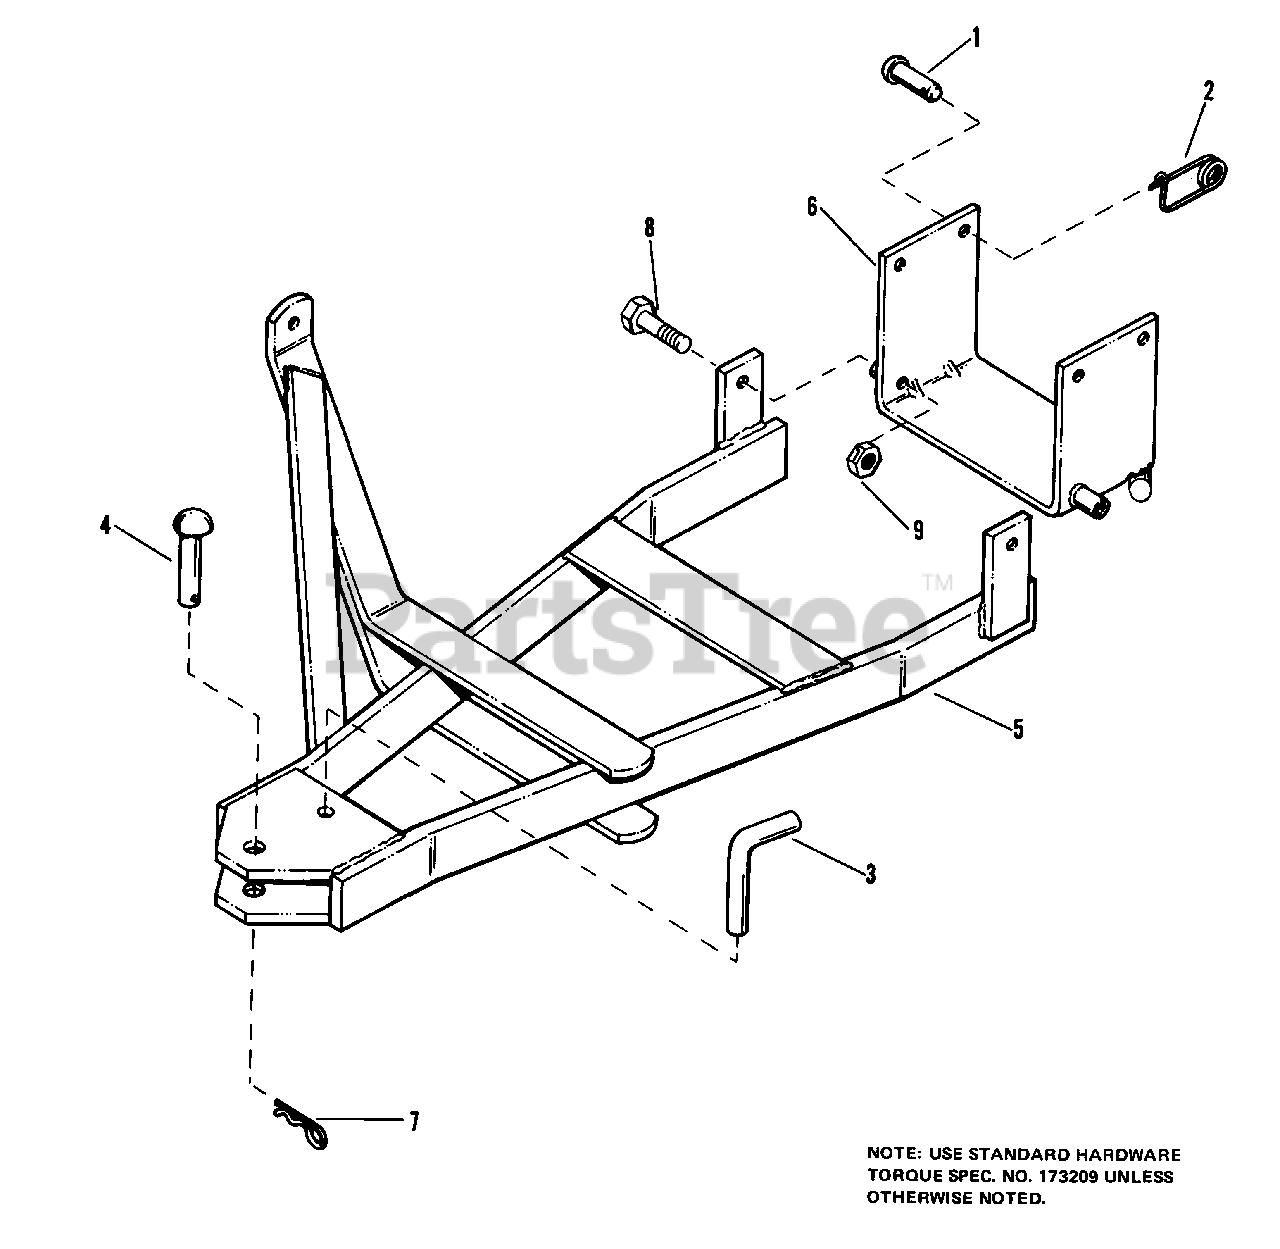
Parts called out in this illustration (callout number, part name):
2	CLIP, Pin, Safety
5	BAR ASSEMBLY, Push
6	BRACKET ASSY
7	CLIP, Spring
8	CAPSCREW, 3/8-16 x 2-1/4
9	LOCKNUT, Flange, 3/8-16
